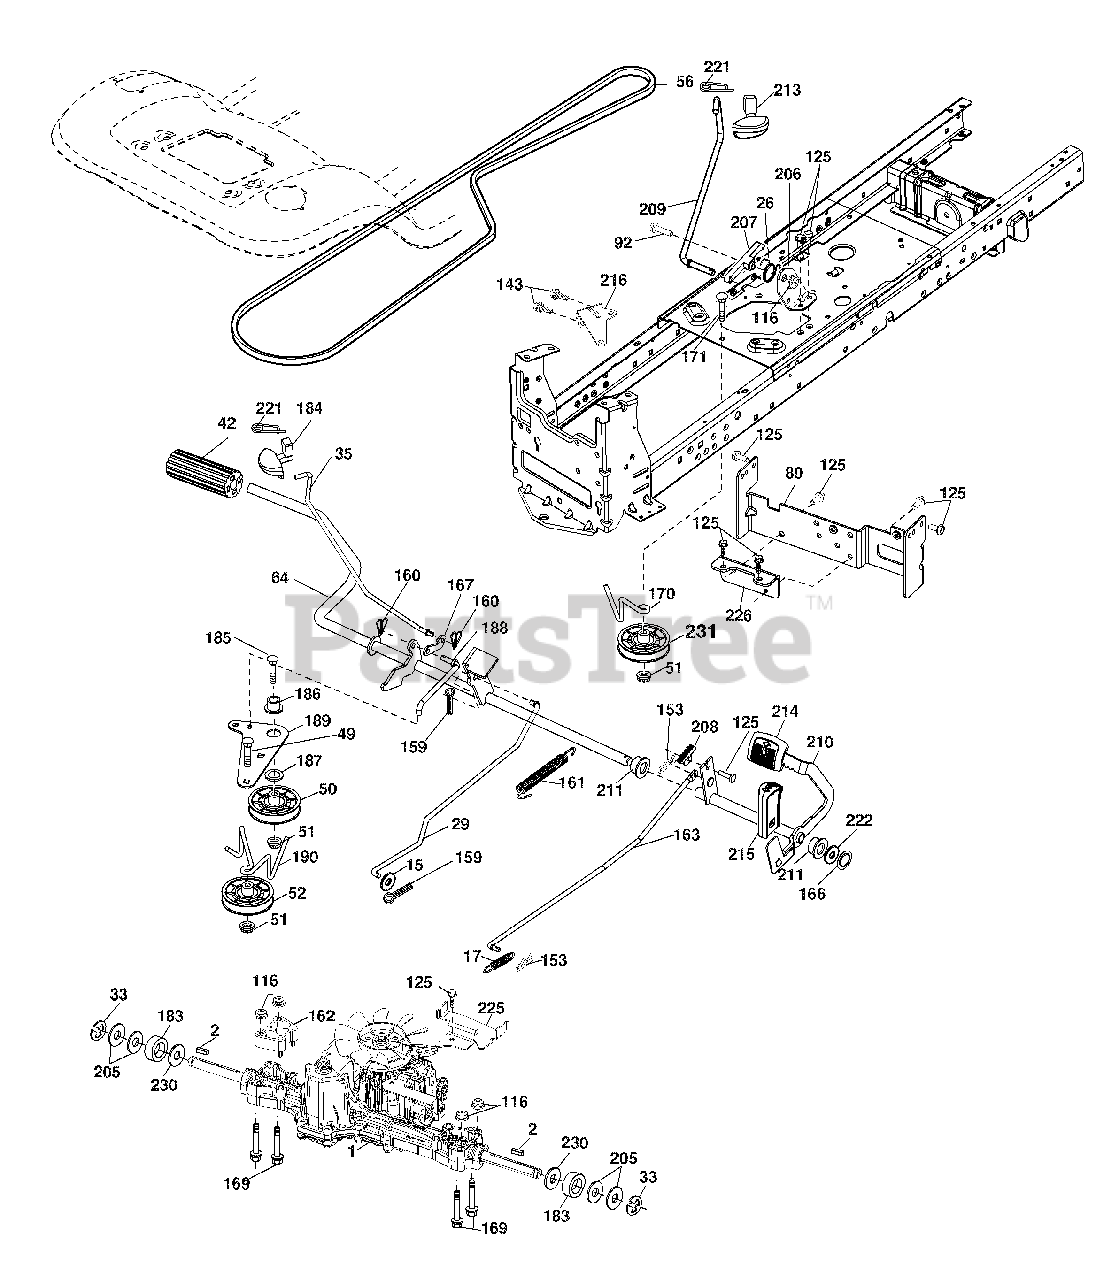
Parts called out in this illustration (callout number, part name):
1	Transaxle, TUFFTORQ K46
2	Key Square
15	Washer 13/32 x 13/16 x 16 Ga.
17	Spring, Brake
26	Spring Return Cruise
29	Rod, Brake
35	Rod, Brake, Park
42	Cover, Foot Pedal
50	Pulley Idler Flat
51	Lock Nut 3/8-16
52	Idler V-Groove 910" Offset
56	V-Belt, Drive
64	Shaft Asm. Pedal Brake Control
80	Strap Torque
92	Bolt Fin Hex 5/16-18 unc x 1.25
116	Nut Lock Hex Flange 5/16-18
125	Screw 5/16-18 x 3/4
143	Screw 5/16-18 x 1/2
153	Retainer Spring
159	Pin Cotter 1/8 x 3/4
160	Retainer Clip
161	Spring, Return, Clutch
162	Spacer Transaxle
163	Rod Pedal Control
166	Nut Push
167	Latch Brake Parking
169	Bolt Hex 5/16-18 x 3.75
170	Keeper Belt Centerspan
183	Spacer Axle
184	Handle Parking Brake
186	Spacer Retainer
187	Washer
188	Link Clutch Ground Drive
189	Bellcrank Ground Drive
190	Keeper Bellcrank Ground Drive
205	Washer 25/32 x 1-5/8 16 Ga.
206	Bracket Mount Latch Cruise
207	Latch Control Cruise
208	Gear Sector Control Cruise
209	Rod Control Cruise
210	Rockr Asm. Pedal Control
211	Bearing Nylon
213	Knob control Cruise
214	Pad Pedal Forward
215	Pad Pedal Reverse
216	Bracket Pulley Idler
221	Retainer Spring Clip
222	Washer 21/32 x 1-1/4 10 Ga.
225	Keeper Bolt Transaxle
226	Bracket Mount Torque
230	Washer Hardened
231	Idler V-Groove 1.688" OFFSET
